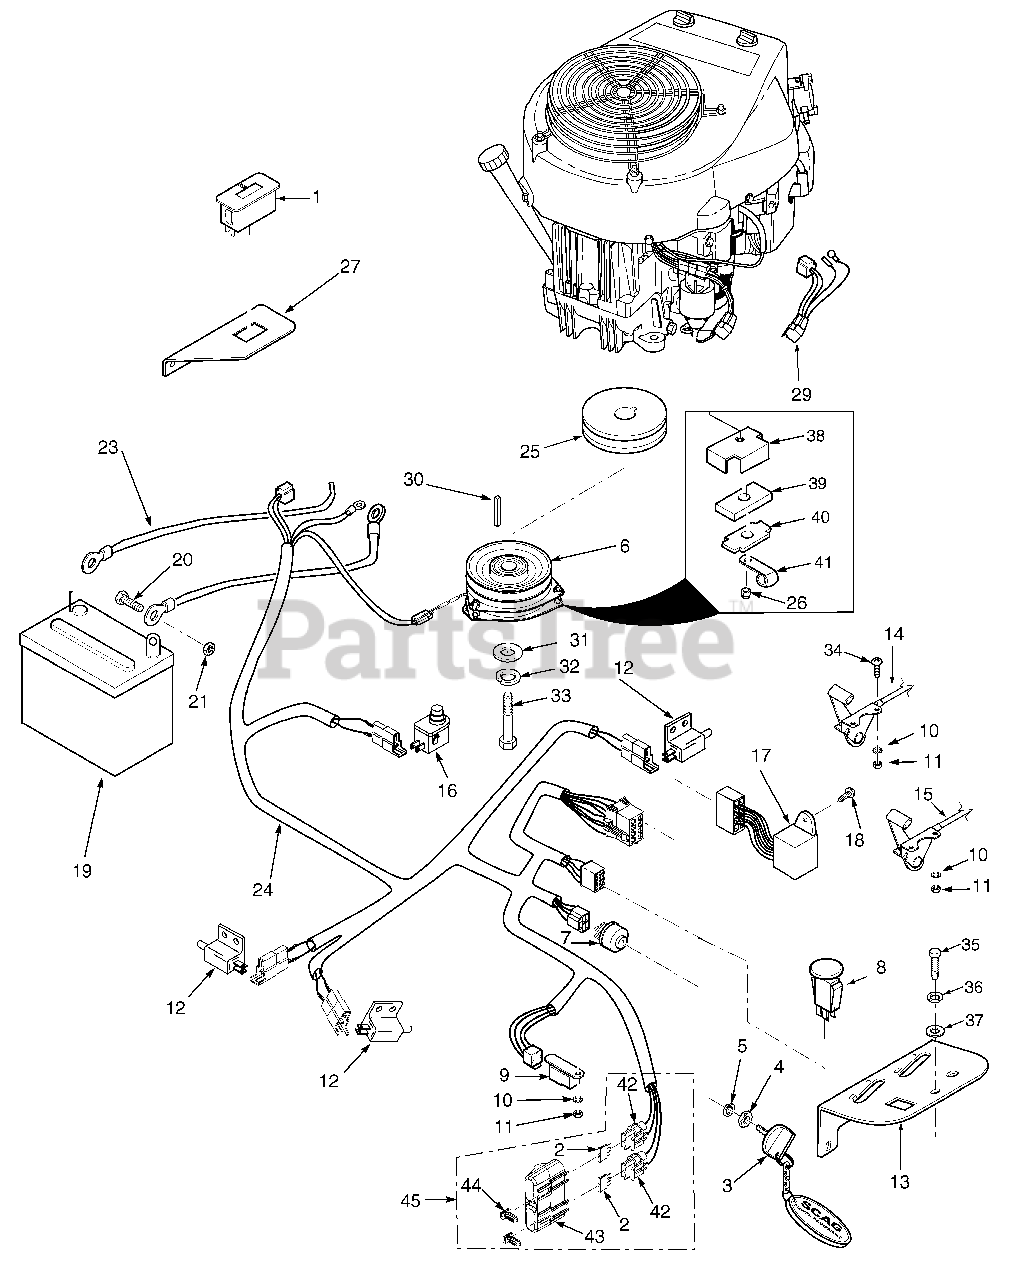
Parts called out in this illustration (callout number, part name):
1	Hourmeter
2	Fuse, 20 amp
3	Key, Ignition
4	Nut, Hex 5/8-32
5	Lockwasher, 5/8" Internal
6	Electric PTO Clutch GT3.5
7	Switch, Ignition
8	Switch, PTO
9	Relay
10	Lock Washer, #10 External Tooth
11	Nut, Hex #10-32
12	Switch, N/O
13	Panel, Instrument
14	Choke & Throttle Control
14	Choke Control
15	Throttle Control
16	Switch, Seat
17	Module, Interlock
18	Screw, #10-32 x .5" Phillips Head
19	Battery, 330CCA
20	Bolt, Hex Head 1/4-20 x .5"
21	Nut, Hex 1/4-20
22	Cable, Battery Black
23	Cable, Battery Red
24	Wiring Harness, Main
25	Pulley, 5.45 OD x 1.125" Bore
26	Nut, Elastic Stop 5/16-18 Key
27	Mounting Bracket, Hour Meter
28	Screw, #10-32 x 1.5" Phillips Head
29	Adaptor, Wiring Harness
30	Key, 1/4 x 1/4 x 3-1/4"
31	Flatwasher, 7/16-.469 x 1-3/4" x 1/4"
32	Lockwasher, 7/16"
33	Bolt, Hex Head 7/16-20 x 2-1/2" UNF
34	Screw, #10-32 x 3/4"
35	Bolt, Hex Head 5/16-18 x 3/4"
36	Lockwasher, 5/16"
37	Flatwasher, 5/16-.375 x .875 x .083
38	Backing Plate
39	Rubber Pad, Clutch Stop
40	Plate, Backing
42	Fuse Holder
43	Cover, Sealed Double
44	Clip, Wire
45	Double Fuse Assembly, Sealed
